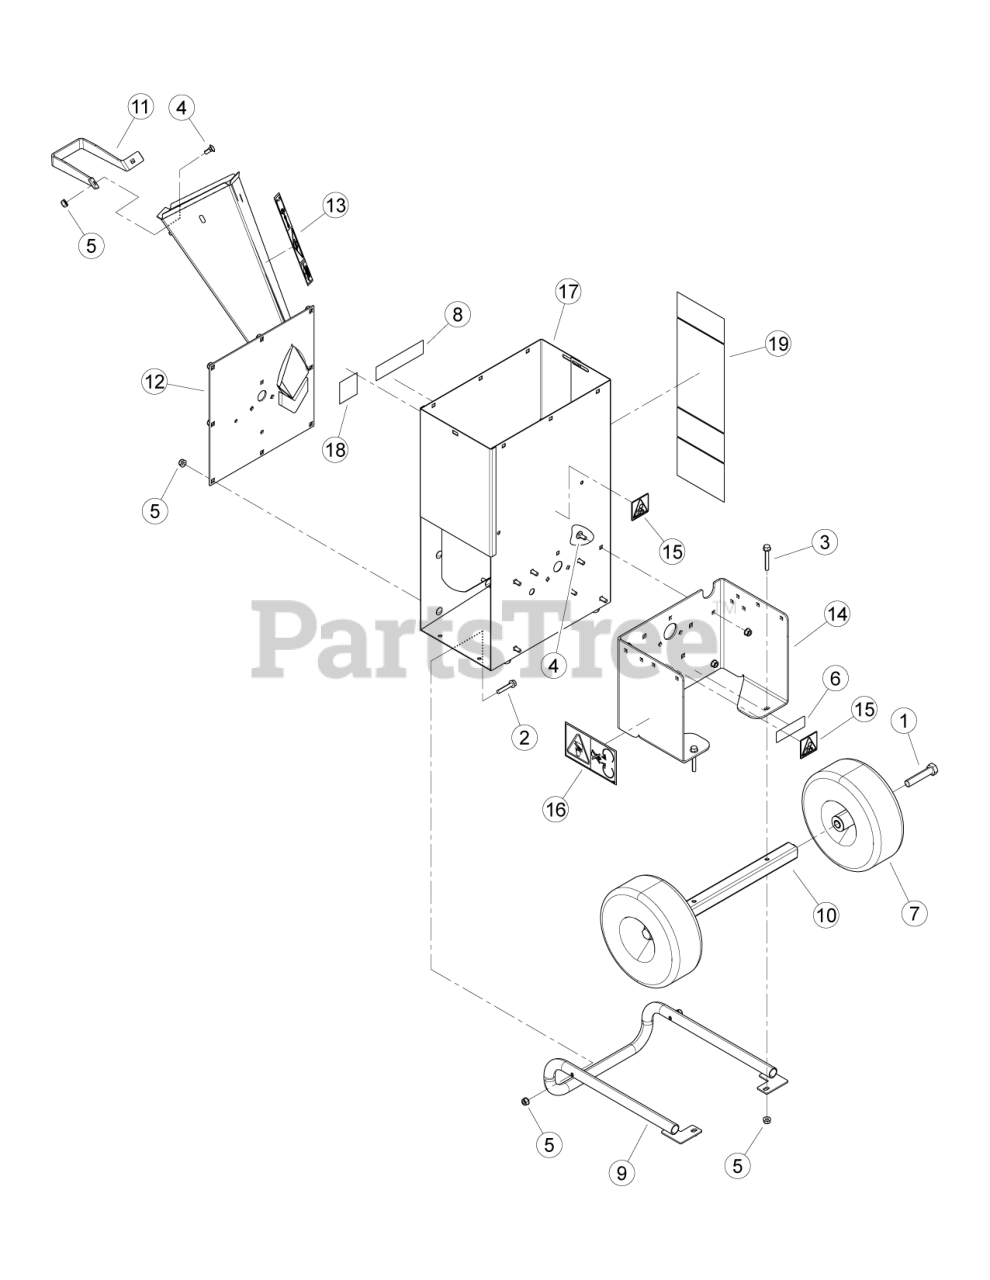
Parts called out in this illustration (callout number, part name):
1	BOLT, 5/8 × 3 HEX HD GR5 ZP
2	BOLT, 5/16 × 1-3/4 FLANGE NC
3	BOLT, 5/16 × 2-1/4 FLANGE NC
4	BOLT, 5/16 × 3/4 GR5 CRG NC ZP
5	NUT, 5/16-18 NYLOCK FLANGE
6	DECAL, SERIAL NUMBER
7	ASSEMBLY, 410/350-4 FLAT-FREE WHEEL
8	DECAL, MODEL SC-4213
9	WELDMENT, SUPPORT LEG LONG
10	WELDMENT, AXLE 3 IN CHIPPER
11	HANDLE, CHIPPER CHUTE 3 IN
12	ASSEMBLY, 3 IN FRONT PLATE
13	DECAL, 3" CHIPPER CHUTE
14	ASSEMBLY, BASE 3 IN CHIPPER SERVICE
15	DECAL, SHIELD DANGER ISO
16	DECAL, BLADE DANGER ISO
17	ASSEMBLY, 3" C/S WIDE BODY SERVICE
18	DECAL, 3" CHIPPER BODY SIDE
19	DECAL, SPARK ARRESTOR
